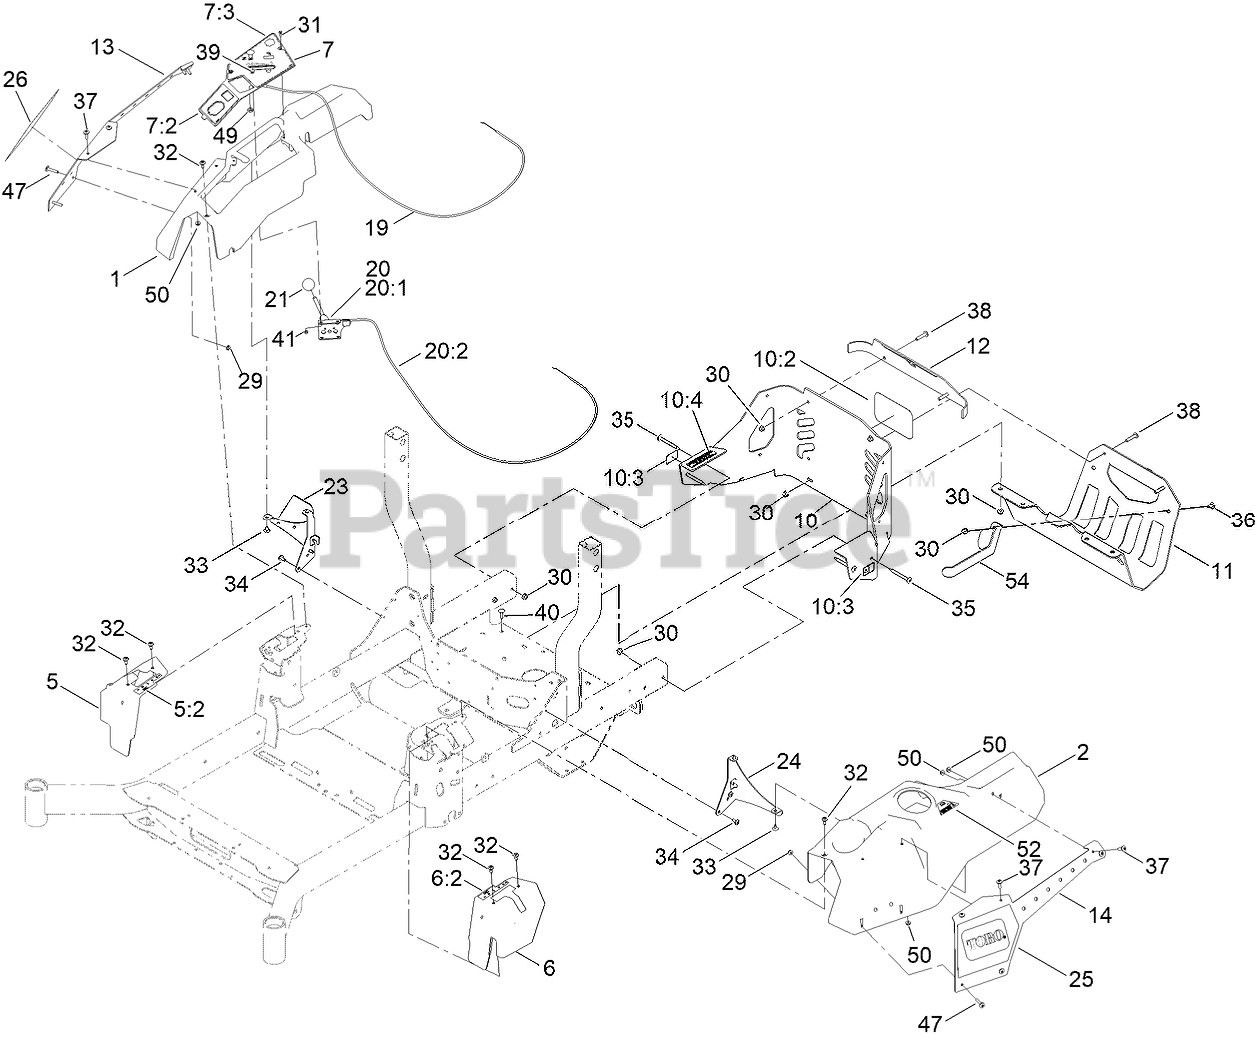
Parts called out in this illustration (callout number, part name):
1	CONSOLE-RH
2	CONSOLE-LH
5	COVER-CONTROL, MOTION (RH)
5:2	DECAL-CONTROL, MOTION (RH)
6	COVER-CONTROL, MOTION (LH)
6:2	DECAL-CONTROL, MOTION (LH)
7	CONTROL PANEL ASM
7:2	DECAL-PANEL, CONTROL
7:3	DECAL-PANEL, CONTROL
10	REAR GUARD ASM
10:2	DECAL
10:3	DECAL-WARNING
10:4	DECAL-ARRESTOR, SPARK
11	GUARD-MUFFLER [BLACK]
12	TRIM-UPPER REAR
13	COVER-POD, RH
14	COVER-LH
19	CABLE-CHOKE CONTROL
20	THROTTLE CONTROL ASM
20:1	LEVER-THROTTLE
21	KNOB-BALL
23	SUPPORT-CONSOLE, RH
24	BRACKET-CONSOLE, LH
25	DECAL-PLATE, LH
26	DECAL-PLATE, RH
29	NUT-HF
30	NUT-HF, NI
31	SCREW-HWH
32	SCREW-SHOULDER
33	SCREW-TORX
34	SCREW-TORX
35	SCREW-TORX
36	SCREW-TORX
37	SCREW-TRUSS
38	SCREW-TORX
39	BOLT-CARR
40	SCREW-CARR
41	NUT-LOCK, NI
47	SCREW-TRUSS
49	NUT-HJ
50	NUT-KEPS
52	DECAL-FILL, FUEL
54	BRACKET-GUARD, MUFFLER
